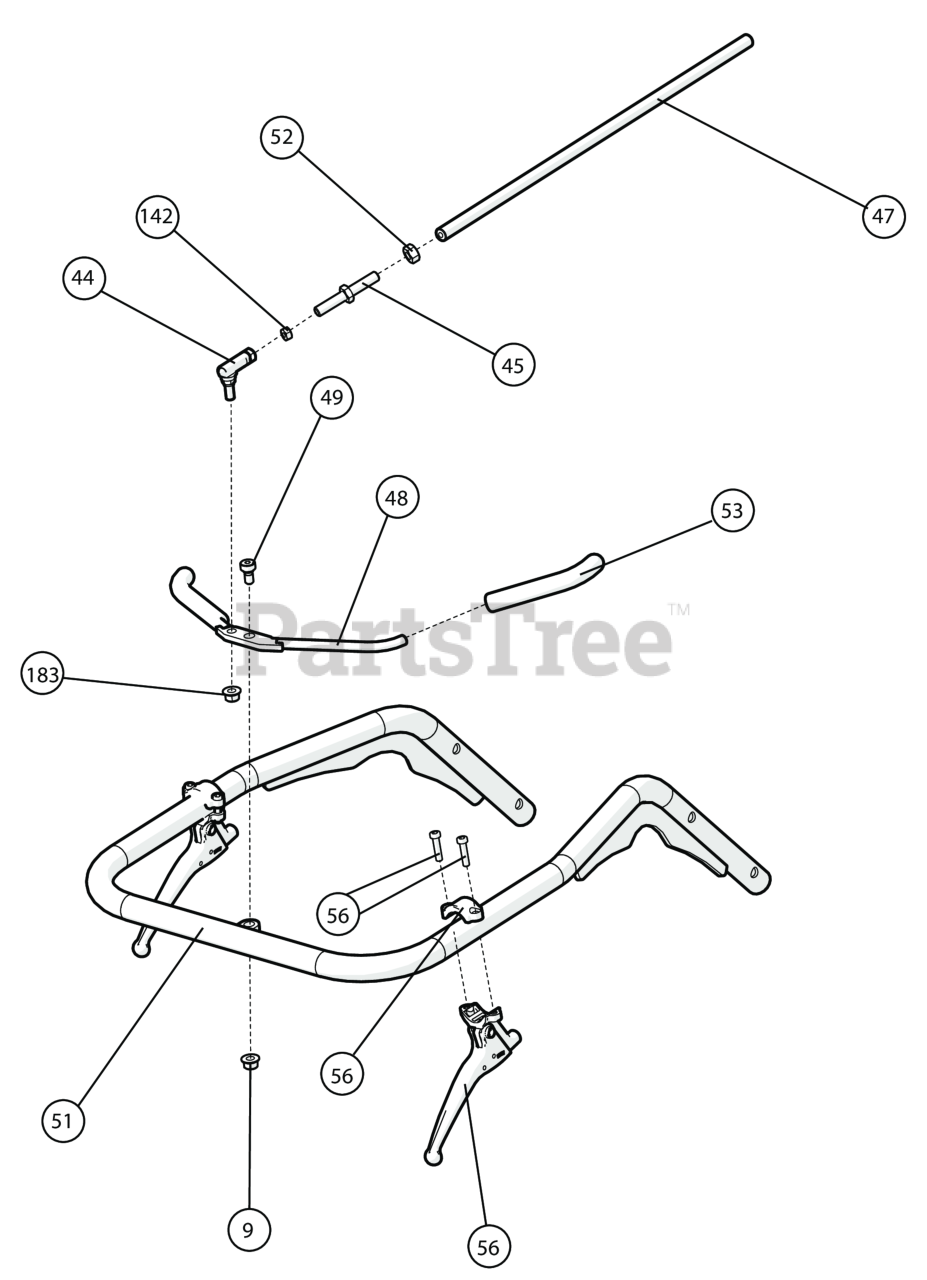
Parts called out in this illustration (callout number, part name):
9	NUT-HEX-NYLK, FLG .3125-18 ZP
44	BALL JOINT, ESL312
45	JACKSCREW 5/16"-24 RT AND LFT
47	ROD, TIE, VALVE CONTROL
48	WA, AUGER DRIVE HANDLE
49	BLT-SLDR,SH.375"X.50",.313"-18X.50"G8ZP
51	WA, DRILL HEAD HANDLE
52	NUT 5/16"-24 LEFT HAND FIN HEX ZP
53	GRIP CLUTCH CONTROL FSP
56	CONTROL MAGURA
142	NUT-HEX, JAM, .3125"-24 G2 YZ
183	NUT-HEX-NYLK, FLG .3125"-24 ZP
